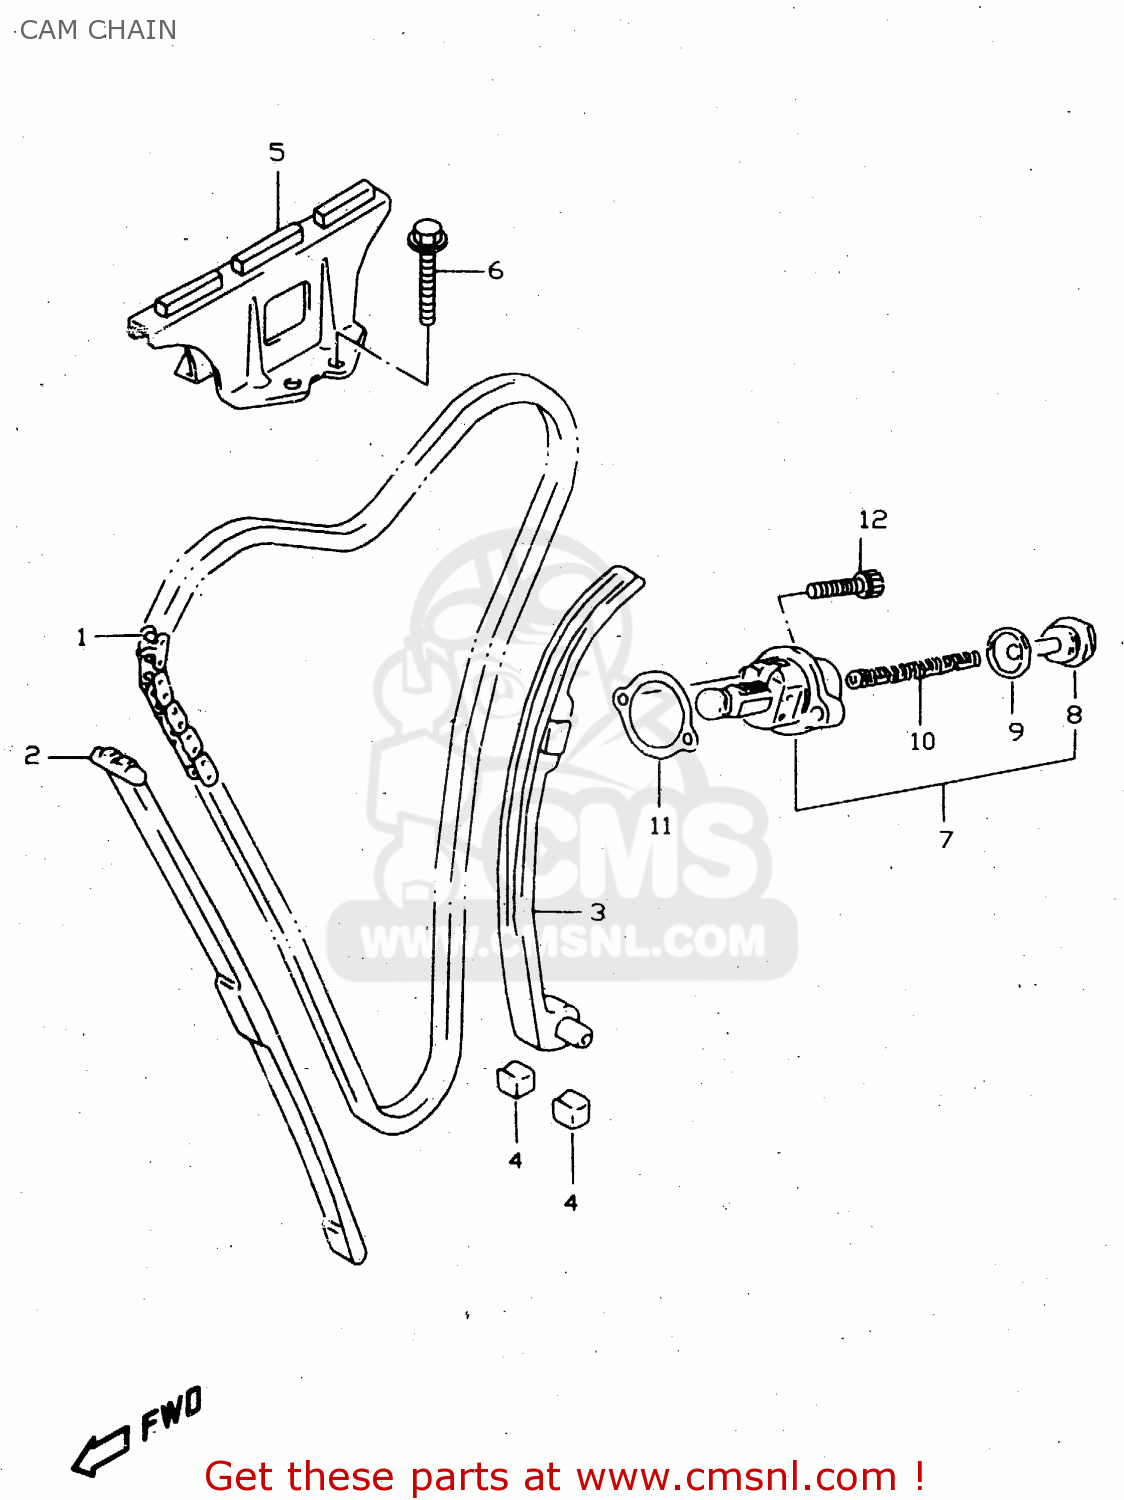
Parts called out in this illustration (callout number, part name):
1	CHAIN,CAMSHAFT DRIVE
2	GUIDE,CAM CHAIN NO.1
3	TENSIONER,CAM CHAIN
4	CUSHION,CAM CHAIN TENSIONER
5	GUIDE,CAM CHAIN NO.2
6	BOLT
7	ADJUSTER ASSY,TENSIONER
8	PLUG
9	GASKET (NAS)
10	SPRING
11	GASKET,TENSIONER ADJUSTER (NAS)
12	BOLT,CL.COVER
